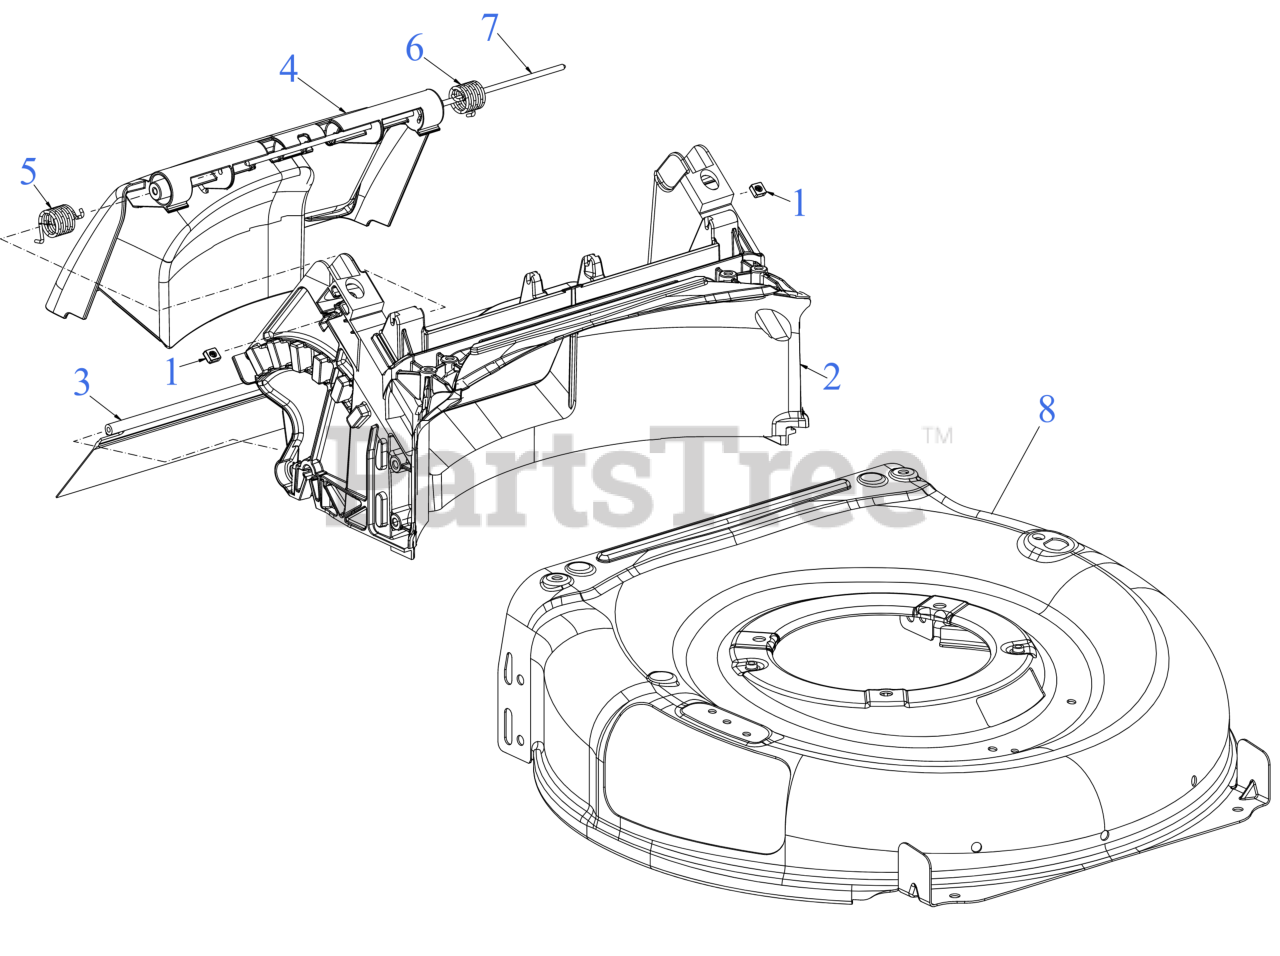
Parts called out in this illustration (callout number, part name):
1	SQUARE NUT 1/4-20
2	REAR DOOR & BAFFLE ASSEMBLY
3	TRAILSHIELD
4	REAR DOOR & BAFFLE ASSEMBLY
5	TORSION SPRING (RH)
6	TORSION SPRING (LH)
7	REAR DOOR PIVOT ROD
